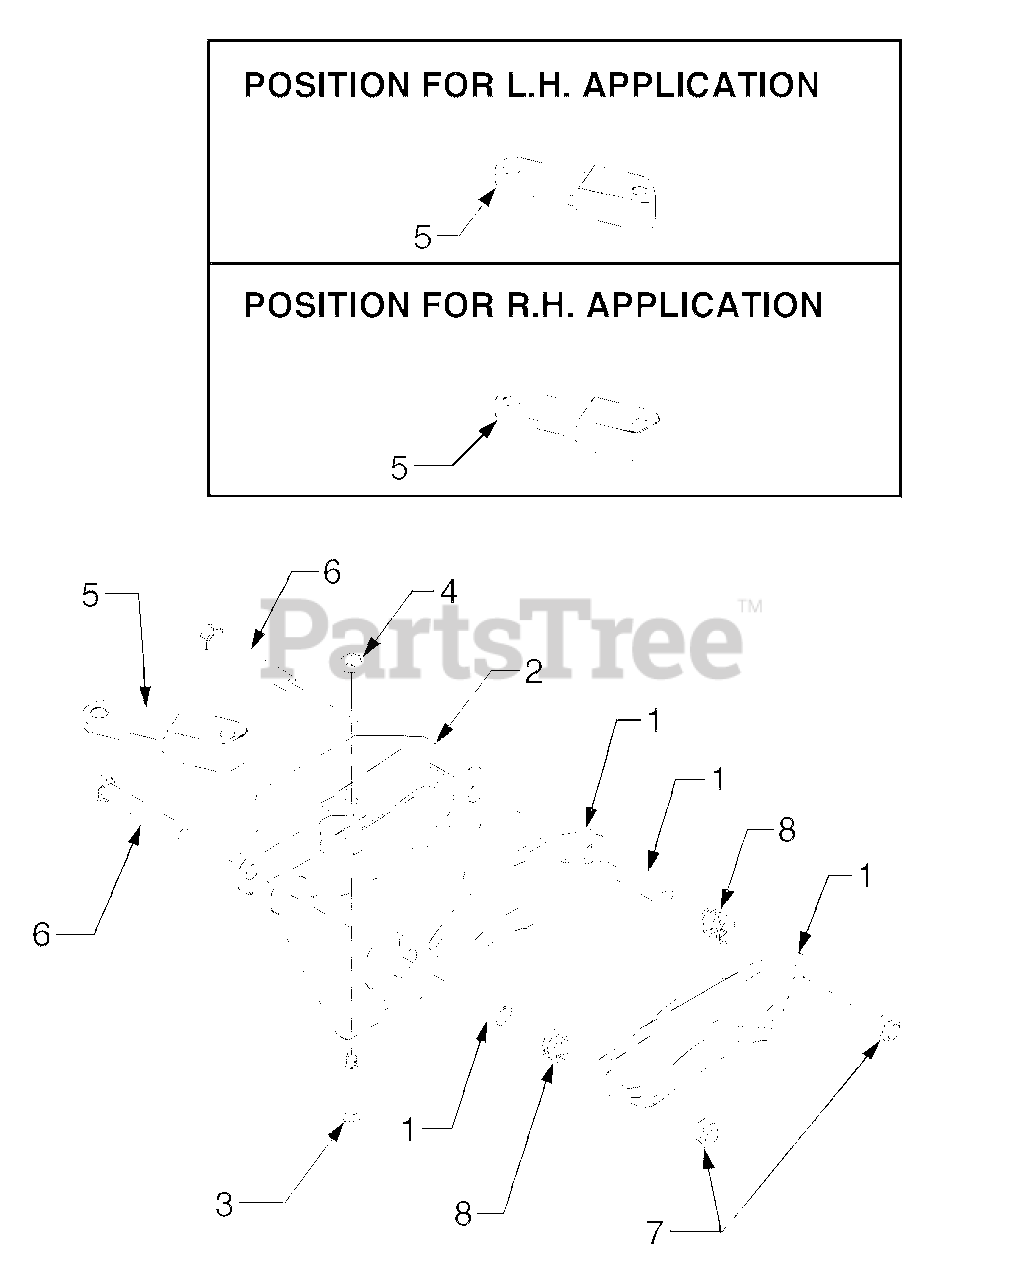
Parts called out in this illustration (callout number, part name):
1	KIT-BRAKE PUCK SVC
2	Bracket, Brake Actuator
3	Screw, Shoulder
4	Nut, Hex Top Lock, 1/4-20
5	Arm, Brake Actuator
6	Screw, Hex Cap, 3/8-24 x 2.5 GR5 4
7	Nut, Hex Lock, 3/8-24
8	Spring, Compression
